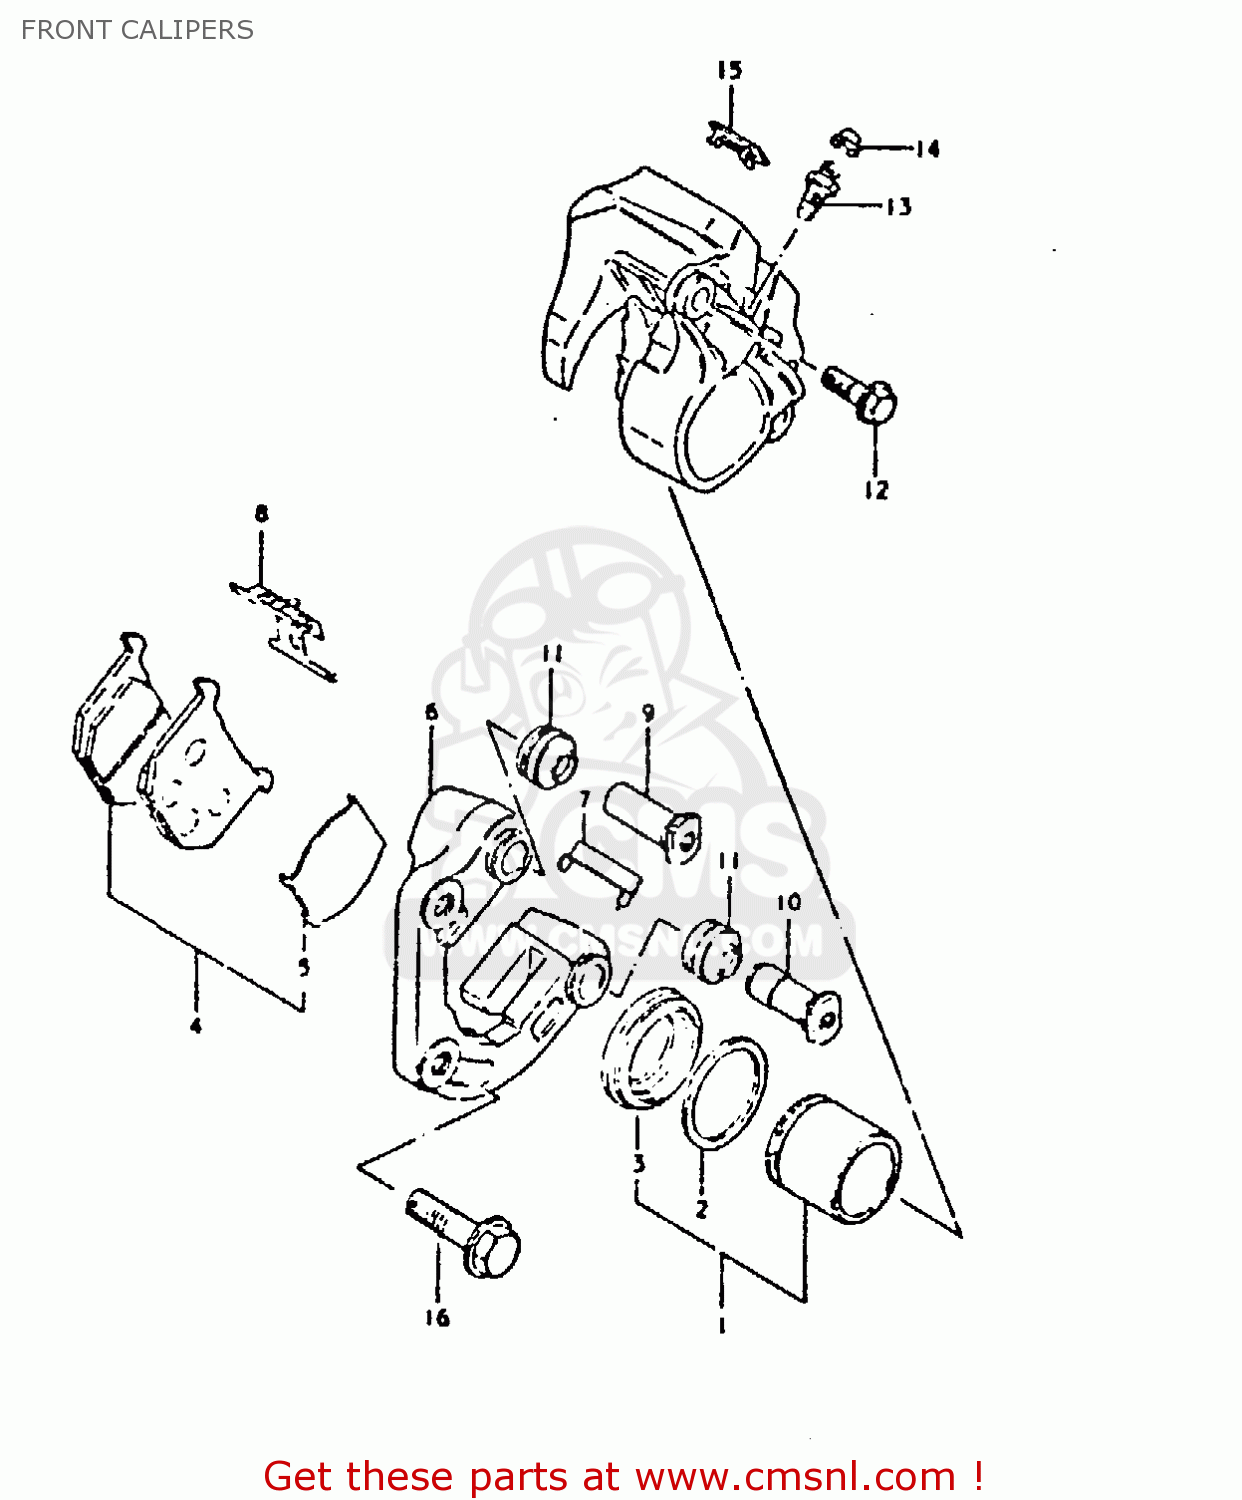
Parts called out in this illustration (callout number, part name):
1	PISTON SET
2	SEAL,FR CALIPE
3	BOOT,PISTON
4	PAD SET (MCA)
5	SHIM,PAD
6	CARRIER,CALIPER,LEFT
7	GUIDE,PAD
8	SPRING,PAD
9	AXLE NO.1
10	AXLE NO.2
11	BOOT,AXLE
12	BOLT,CALIPER HOUSING
13	BLEEDER
14	CAP,BREATHER
15	COVER,INDICATOR
16	BOLT(10X37)
